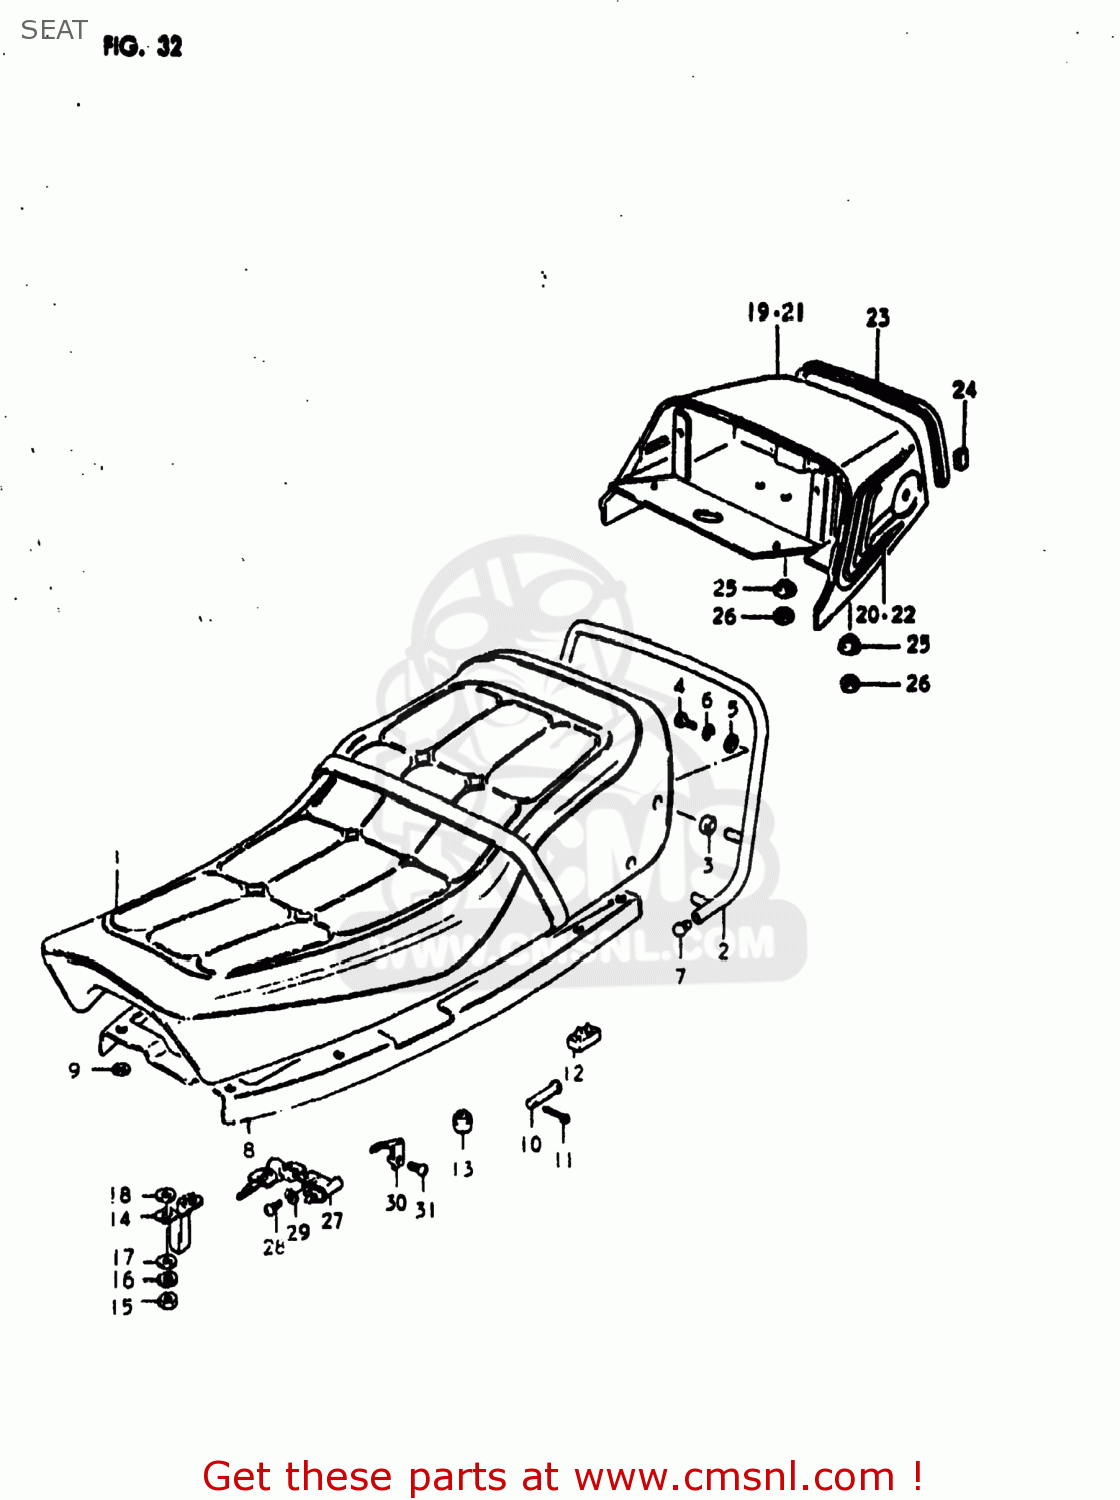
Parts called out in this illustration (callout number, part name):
1	SEAT ASSEMBLY
2	HANDLE,PILLION RIDER
3	CUSHION
4	BOLT
5	WASHER
6	LOCK WASHER
7	END,SHEET HANDLE
8	MOLDING,SEAT
9	NUT
10	PIN
11	PIN
12	CUSHION
13	CUSHION
14	STRIKER,SEAT LOCK
15	NUT
16	LOCK WASHER
17	WASHER
18	WASHER (6.5X20X1.2)
19	COVER SET,SEAT TAIL
21	COVER SET,SEAT TAIL
22	TAPE SET,SEAT TAIL COVER
23	GROMMET
24	CLIP,SEAT TAIL COVER M
25	WASHER
26	NUT 6MM
27	LOCK ASSY,SEAT
28	SCREW
29	LOCK WASHER
30	SPRING,HELMET HOLDER
31	SCREW
